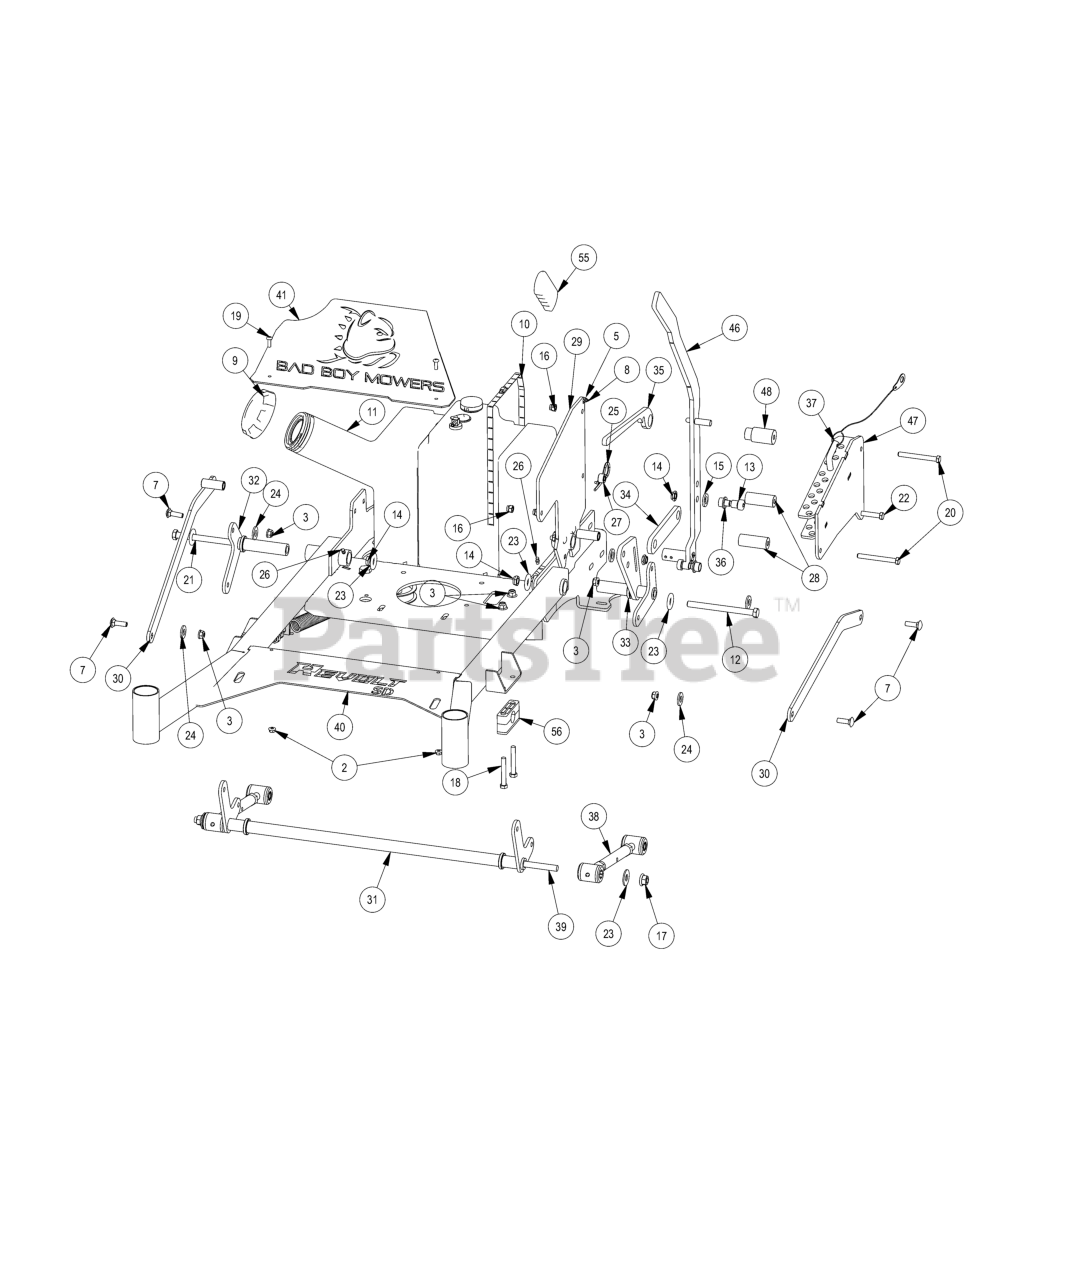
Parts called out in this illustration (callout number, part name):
1	5/16-18 HEX SERRATED FLANGE NUT HARD/ZINC
2	1/4-20 NYL INSERT FLANGE LOCKNUT ZINC
3	3/8 Nylock Flange Nut
4	5/16-18 NYLON INSERT FLANGE LOCKNUT ZINC
5	10-24 NYLON INSERT LOCKNUT ZINC
6	5/16-18 X 1-1/4 CARRIAGE BOLT ZINC
7	3/8-16x 1-1/4 Carriage Bolt
8	10-24 X 5/8 BUTTON SOCKET CAP SCREW 18-8 STAINLESS STEEL
10	Tank Strap
11	2019 REVOLT FUEL TANK
12	1/2-13 X 6 HEX CAP SCREW (GR.5) ZINC
13	5/8 X 5/8 SOCKET SHOULDER BOLT ZINC YELLOW
14	1/2-13 Nylon Insert Jam Locknut
15	.635 ID X 1.120 OD X .140 THICK FLAT WASHER NYLON
16	3/8-16 NYLON INSERT LOCKNUT ZINC
17	1/2-13 NYLON INSERT FLANGE LOCKNUT ZINC
18	3/8-16 x 2 1/2" Hex Bolt
19	1/4"-20 x 3/4 Black Oxide 18-8 Stainless Pan Head
20	3/8-16 X 3-1/2 HEX CAP SCREW (GR.5) ZINC
21	1/2-13 X 5 1/2 HEX CAP SCREW (GR.5) ZINC
22	3/8-16 X 4-1/4 HEX CAP SCREW (GR.5) ZINC
23	1/2 Flat Washer
24	.505 Nylon Spacer
25	Revolt Cotter Pin for 7/8" to 1" shank
26	1/4 DRIVE-TYPE STRAIGHT GREASE FITTING (NO BALL) ZINC YELLOW
27	ACS Spacer 3/4x3/8x1/2
28	Stand On Spacer 2.5''
29	2023 SD Inner Adjustment Plate
30	2023 SD-36 Stand-on Actuator Linkage
31	Revolt Front Actuator Bar Weldment - Raw 2020 36" Black
32	Revolt Rear Actuator Bar Weldment RH 2020 36" Black
33	2023 SD Actuator rear_LH
34	2023 lever secondary linkage
35	2019 Stand On Deck Lever Lock
36	.627 ID X .753 OD X .500 LGTH X 1.000 FLG OD X .094 FLG THICK FLANGED BEARING OIL-IMPREG BRNZ
37	2023 stand on Height Adj Pin
38	2018 Maverick Turnbuckle (Top Link)
39	2020 36 Stand On Turnbuckle Rod
40	2023 Stand On Frame Weldment -SD
41	Exhaust Shield SD
42	1/2-13 HEX NUT ZINC
43	All Thread
44	5/8-11 NYLON INSERT LOCKNUT ZINC
45	Deck spring big diameter
46	2023 Stand On SD Lift Lever Weldment
47	2023 Stand On Outer Adjustment Plate weldment
48	Stand On Spacer 2.5'' With shoulder
49	36 Pump Idler Arm Weldment
50	3.25 Flat Idler Pulley
51	1/4" Press in Grease Fitting
52	1/2-13 X 2-1/4 HEX CAP SCREW (GR.5) ZINC
53	5/16-18 NYL INS L/N ZC
54	.565 ID X 1.250 OD X .095 THK FLAT WASHER BRASS
55	2019 Stand On Lift Grip
56	Pillow Block Kit
